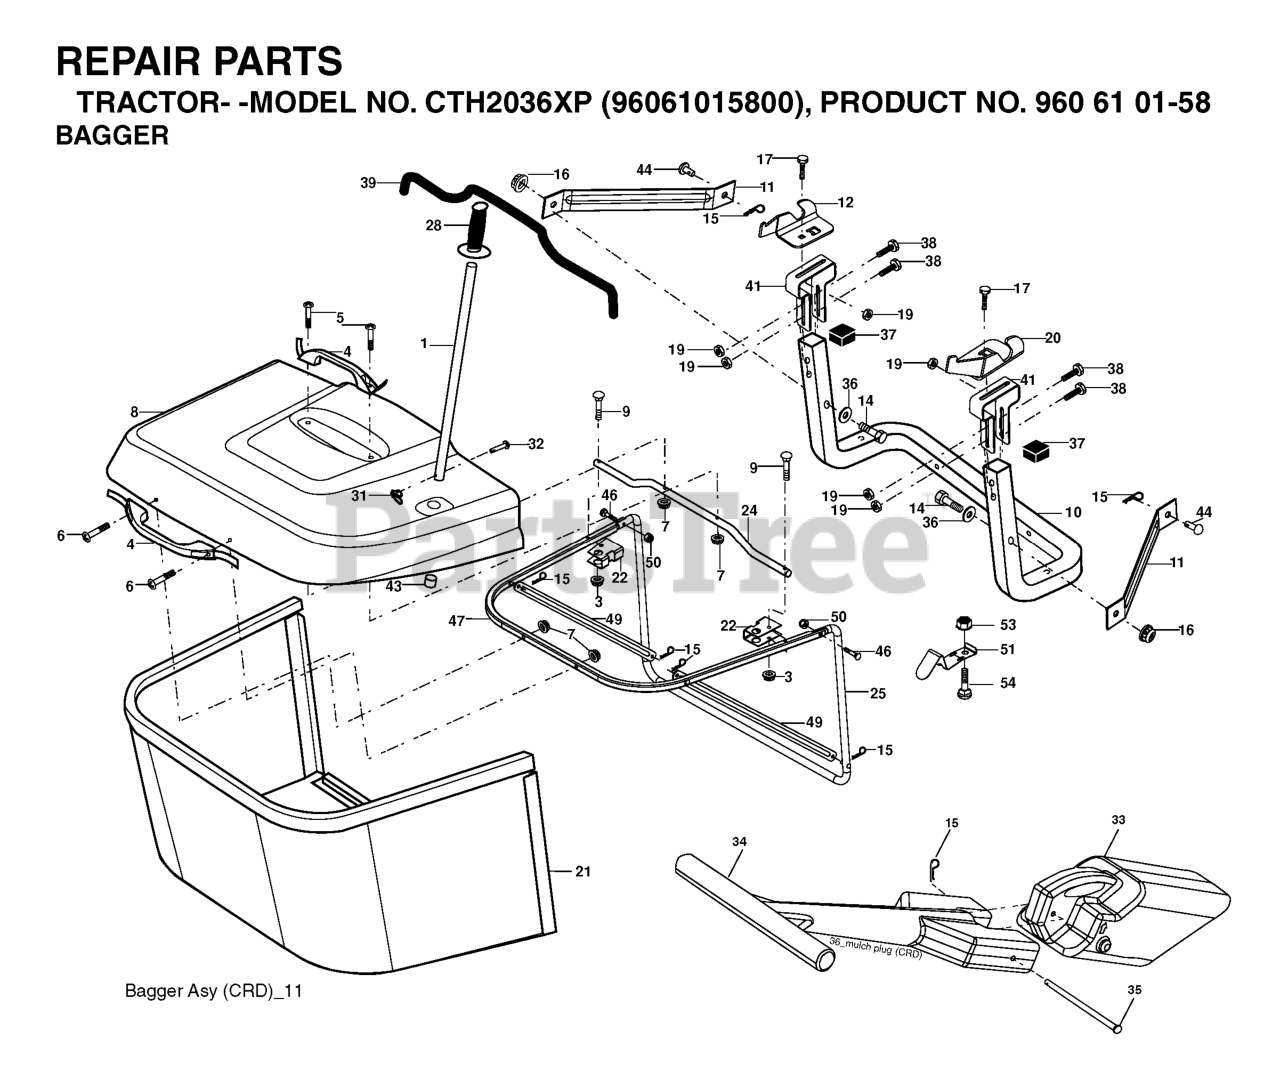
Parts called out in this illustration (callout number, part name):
1	TUBE HANDLE
3	NUT T
4	HANDLE.BAGGER.W/LVRS.BLK.CRD
5	SCREW.PAN.HEAD
6	REPL BY 532 75 00-29
8	COVER.PNT.BGR.CRD.WSLOTS.MS668
9	Bolt Carriage 1/4-20 x 2.25d x Gr.5
10	TUBE
11	BRACKET.SUPPORT.UPPER.BAG.CRD
12	BRKT PIVOT
14	BOLT-HEX EAK
15	RETAINER-SPRNG RB
16	NUT LOCK FLG 3/8-16 UNC
17	RP BOLT 5/16-18 X3/4 ZN/YEL GR
19	NUT LOCK HEX FLANGE 5/16-18
20	BRKT.PIVOT.RH.CRD
22	BRKT.SIDE.BAG.CRD
24	TUBE.PIVOT.BAG.CRD.BLACK
25	PIPE
28	GRIP.HANDLE.BLACK
31	RETAINER CLIP
32	RIVET,DRILLED
33	PLUG.MULCHER.92 CRD
34	HANDLE.MULCHER.92.CRD (2 2)
36	WASHER
37	Plug Support Bagger CRD
38	BOLT.5/16-18X2.5
39	SEAL.TRIM.37'
41	BRKT.VERT.ADJ.BAGGER.CRD
43	PLUG, TUBING END
46	BOLT.CARRIAGE.5/16-18
47	PIPE
49	ROD
50	NUT.71038.31-18.HEX.NYLOCK
51	LATCH
52	BOLT
53	NUT
